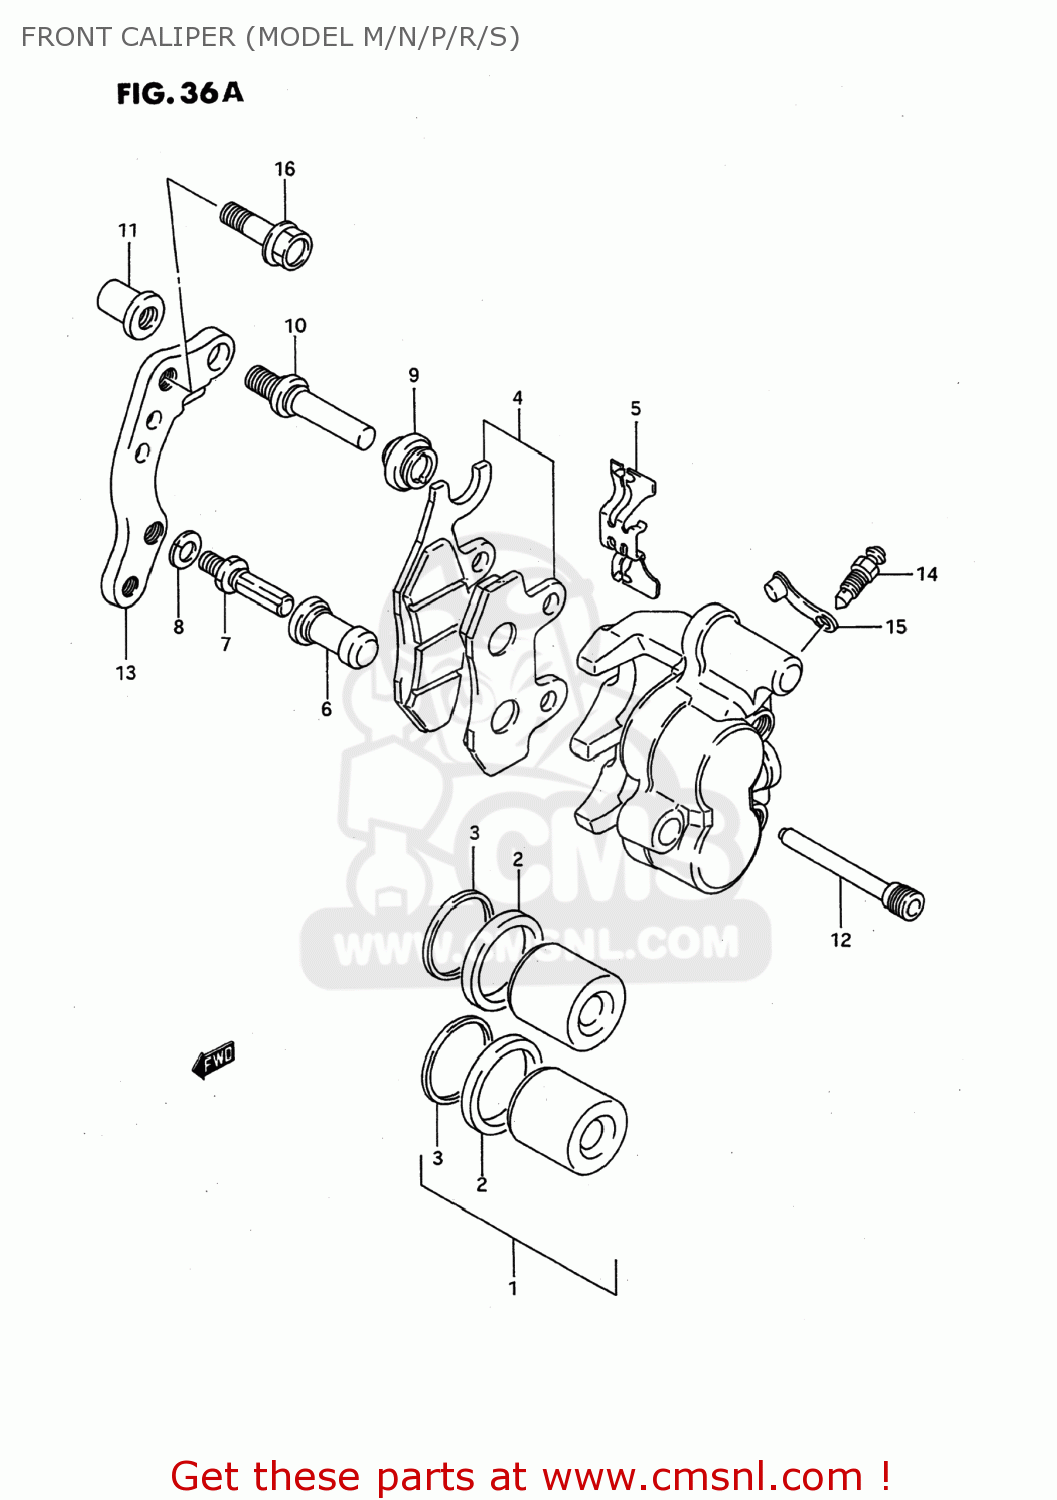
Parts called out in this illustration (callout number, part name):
1	PISTON SET
2	SEAL,PISTON
3	SEAL,DUST
4	PAD SET (NAS)
5	SPRING,PAD
6	BOOT
7	BOLT,PIN
8	WASHER,WAVE
9	BOOT
10	PIN,SLIDE
11	NUT
12	PIN,HOLDER
13	BRACKET
14	BLEEDER
15	CAP,BLEEDER
16	BOLT(8X35)
